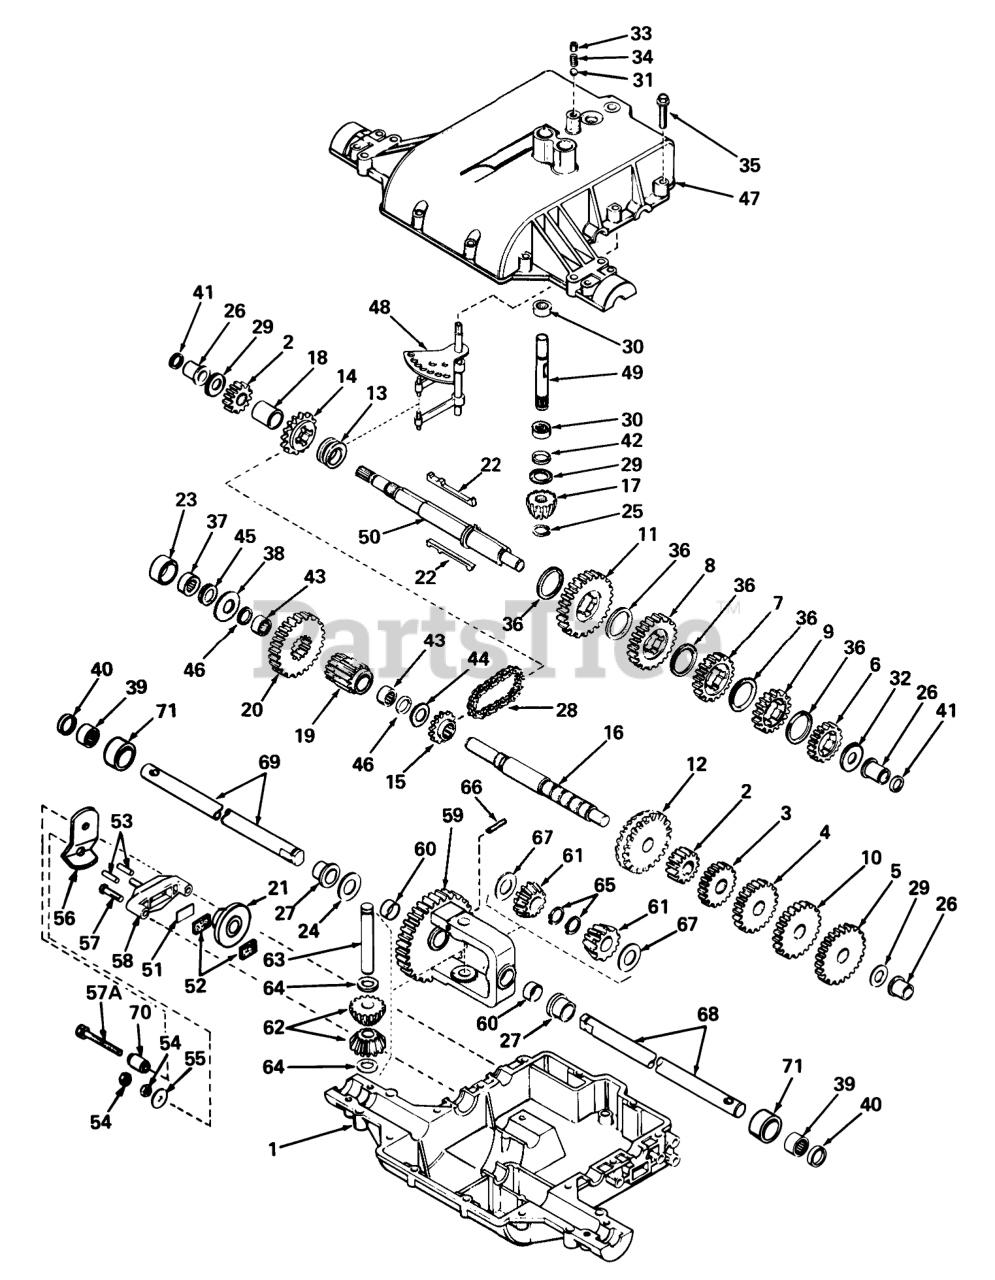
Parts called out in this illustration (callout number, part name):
1	Case, Transaxle
2	Gear-Spur 15 Teeth
3	Gear, Spur (20 teeth)
4	Gear, Spur (25 teeth)
5	Gear, Spur (30 teeth)
6	Gear-Spur 20 teeth
7	Gear, Spur (25 teeth)
8	Gear, Spur (30 teeth)
9	ASpur Gear (22 Teeth)
10	Gear, Spur (28 teeth)
11	Gear-Spur, 35 Teeth
12	Gear, Bevel (42 teeth)
13	Collar-Shift
14	Sprocket-18 Teeth
15	Sprocket-9 Teeth
16	Shaft-Counter
17	Bevel Pinion-Input
18	Spacer
19	Pinion-Output
20	Gear-Output
23	Spacer
24	Washer
25	Ring-Retainer
26	Bushing, Flanged
27	Bronze Bearing
28	Chain-Roller #41
29	Washer
30	Bearing-Needle
31	Ball-Steel
32	Washer
33	Screw-Set
34	Spring
35	Ring Set (.020 O S)
36	Washer
37	Bearing-Needle
38	Washer-Flat
39	Bearing-Cartridge
40	Seal Oil
41	Ring-Square Cut
42	O Ring
43	Bearing-Needle
44	Washer-Flat
45	Ring-Square Cut
46	Ring-Square Cut
47	Cover, Transaxle
48	Rod & Fork Assembly
49	Shaft, Input
50	Shaft, Brake
51	Brake Pad Plate
52	Brake Pad
53	Dowel Pin
54	Locknut
55	Washer
56	Lever-Brake
57	Ring Set (.020 O S)
57A	Screw-Hex. Flange
58	Holder-Brake Pad
59	Gear Assembly, Differential (Incl. 2 of No. 60)
60	Bushing
61	Bevel Gear
62	Gear Pinion
63	Drive Pin
64	Thrust Washer
65	Snap Ring
66	Pin-Roll
67	Washer
68	Axle (14-7/8" Long)
69	Axle (13" Long)
70	Spacer
71	Sleeve
